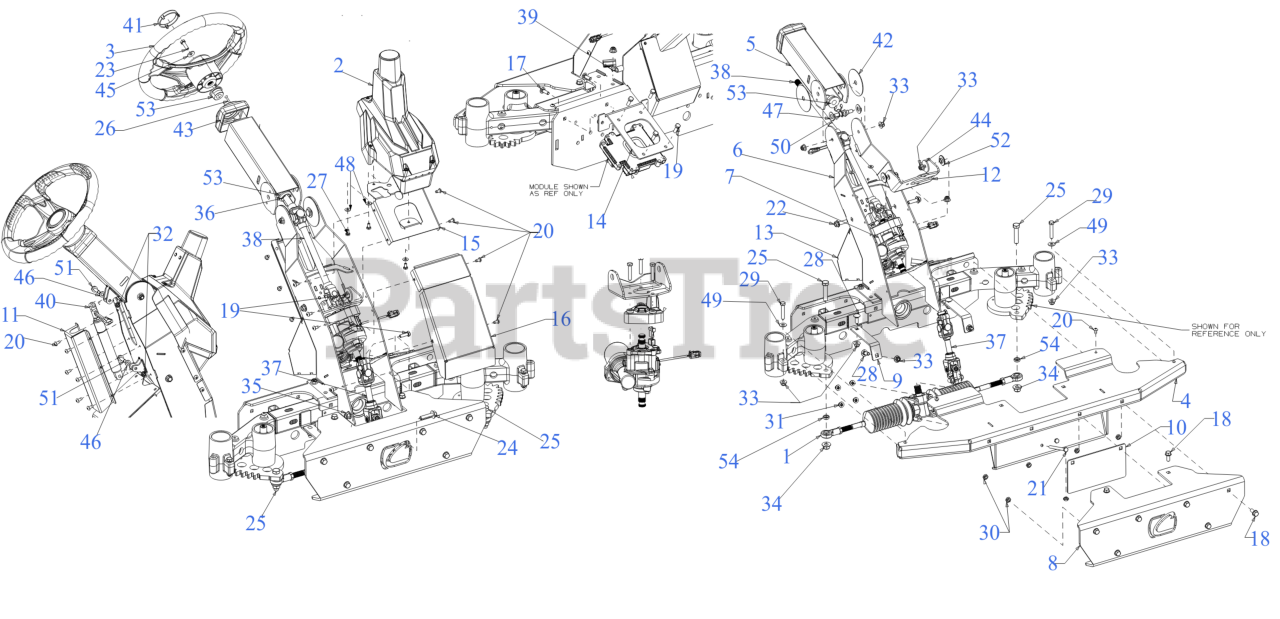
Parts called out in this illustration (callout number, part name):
1	STEERING GEARBOX
2	GPM ASSEMBLY
3	STEERING WHEEL
6	TILT COLUMN
7	POWER STEERING (W/MDL & HARN)
8	FRONT BUMPER UPPER COVER
12	BRKT:EPS:TOP:AUTOSTEER
13	EPS COLUMN COVER
14	POWER STEERING BRACKET
15	GPM BRACKET
16	COLUMN COVER (LOWER)
17	CARRIAGE BOLT 5/16-18 x 1.00
18	SCREW 3/8-16 x .875 GR5
19	SCREW M8-1.25 x 25 GR8.8
20	SCREW 1/4-20 x .5
21	SCREW 5/16-18 x 4.00 GR5
22	SCREW 3/8-16 x 1.25 GR5
23	SCREW 5/16-18 x 1.00 GR5
24	HEX FLANGE BOLT M10-1.50
25	HEX HEAD CAP SCREW 1/2-13x2.25 GR8
26	SCREW #10-16 x 1.25
27	SCREW 1/4-20X.5 GR5
28	CARRIAGE BOLT 3/8-16 x 1.00 GR5
29	SCREW 3/8-16 x 2 GR5
30	JAM LOCK NUT
31	FLANGE LOCK NUT 5/16-18
32	FLANGE LOCK NUT
35	HEX FLANGE NUT M10-1.50
37	LOWER STEERING SHAFT
38	STEERING SHAFT (UPPER)
39	J TYPE CLIP
40	TILT STEERING DAMPENING CYLINDER
41	STEERING WHEEL CAP
42	COLUMN PLATE
43	STEERING COLUMN COVER
44	FLAT WASHER .390x1.500x.134
45	BELL WASHER .337 X.867 x .057
46	FLAT WASHER
47	TEFLON WASHER .570x1.120x.062
48	FLAT WASHER
49	FLAT WASHER .401X.88
50	SHOULDER SCREW .498 DIA x .340
51	SHOULDER SCREW
52	SHOULDER SPACER
53	FLANGE BEARING
